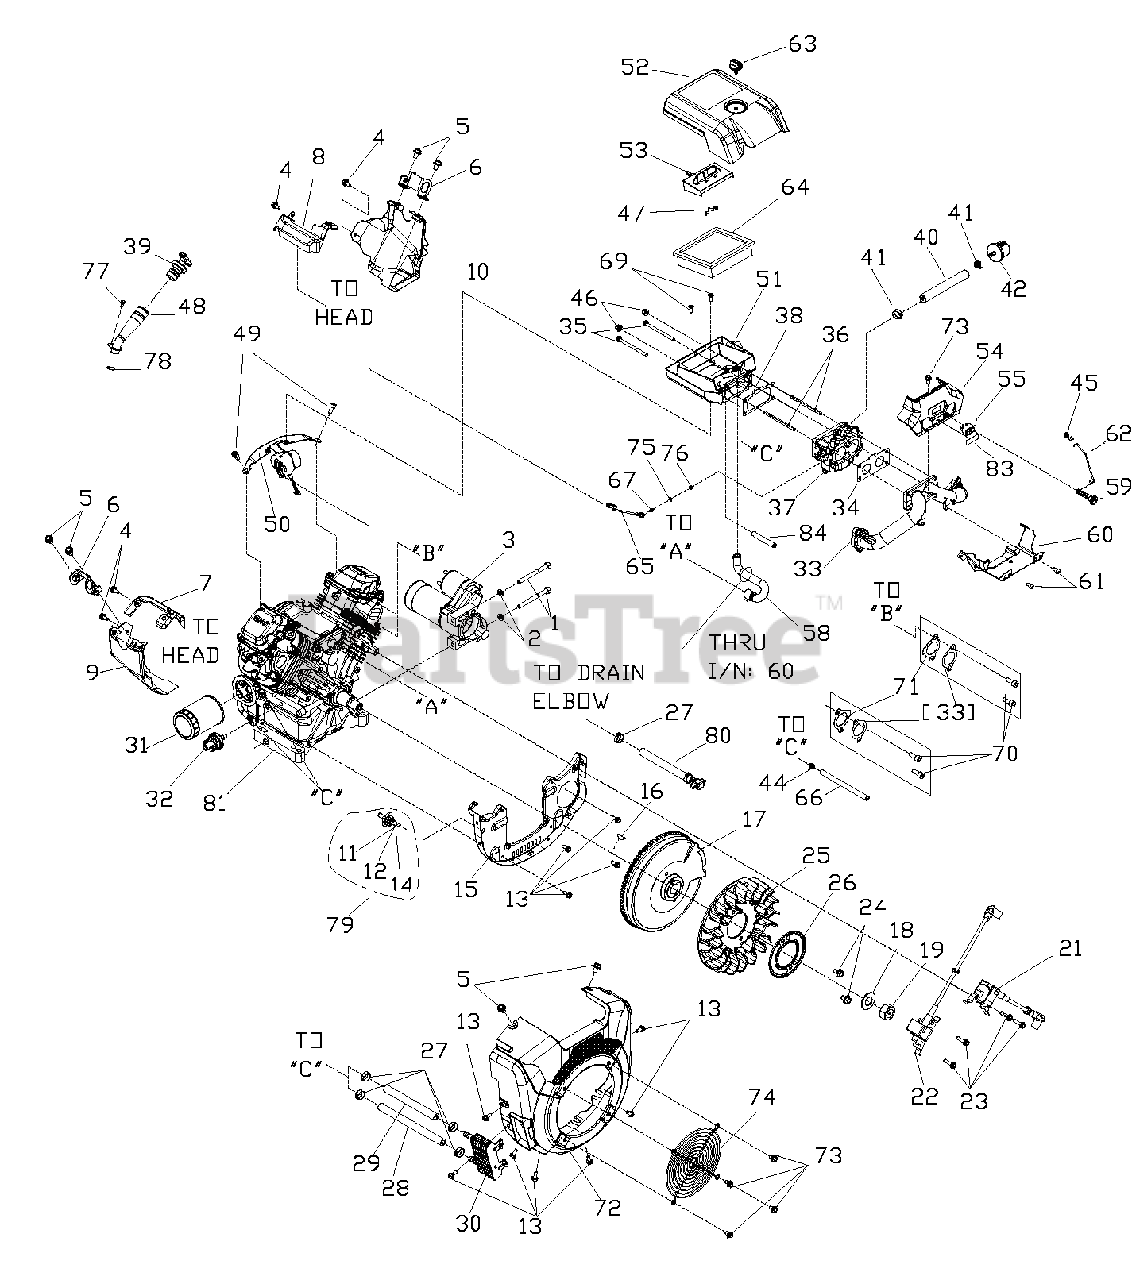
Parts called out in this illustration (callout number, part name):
1	SCREW HHC M8-1.25 X85
2	WASHER LOCK M8-5/16
3	STARTER MOTOR
4	SCREW HHFC M6-1.0 X 12
5	SCREW HHFC M8-1.25 X 14
6	LIFTING HOOK
7	WRAPPER INNER CYL #2
8	WRAPPER INNER CYL #1
9	WRAPPER OUTER CYL #2
10	WRAPPER OUTER CYL #1
11	SCREW CONNECTOR
12	GROUND POST MOUNT BLOCK
13	SCREW HHFC M6-1.0 X 8
14	NUT HEX M5 X 0.8
15	BACKPLATE GT530
16	KEY WOODRUFF 4X19
17	ASSY FLYWHEEL & RING 29 DEG
18	WASHER BEL V-20 X 2.2
19	HEX NUT METRIC
21	ASSY IGN COIL W/DIODE CYL #1
22	ASSY IGN COIL W/DIODE CYL #2
23	SCREW HHC M6-1.25 X 25 SEMS
24	SCREW HHFCS M8-1.25 X 12
25	FAN FLYWHEEL
26	PLATE FAN
27	CLAMP HOSE OETIKER STEPLESS 18.5
28	HOSE 3/8" PUSH-ON (191MM)
29	HOSE 3/8" PUSH ON (152MM)
30	OIL COOLER
31	FILTER OIL 90MM NO BRAND
32	SWITCH LOW OIL PRESSURE
33	MANIFOLD INTAKE GT530
34	GASKET INTAKE MANIFOLD TO CARB/MIXER
35	BOLT CARB MOUNT
36	STUD M6-1.0 X 90 DRI-LOC
37	CARBURETOR
38	GASKET AIRBOX TO CARB / MIXER
39	ASSY DIPSTICK
40	HOSE 1/4" GREENBAR SAE30R7 6"
41	CLAMP HOSE BAND 0.530
42	FILTER, FUEL
44	CLAMP HOSE BAND 0.409
45	BUSHING GOVERNOR ROD
46	NUT FLANGE M6-1.0 NYLOK
47	SPRING SUMMER / WINTER
48	ASSY OIL CHECK AND FILL
49	SCREW SHC M8-1.25 X 16
50	ELECTRONIC GOVERNOR STEPPER MOTOR
51	BASE AIRBOX
52	COVER AIRBOX
53	VALVE SUMMER / WINTER
54	COVER FRONT GTH530
55	SWITCH MOMENTARY (OFF) - ON
58	BREATHER HOSE
59	KNOB CHOKE
60	BAFFLE CENTER
61	SCREW BHSC M6-1.0 X 12
62	ROD MANUAL CHOKE
63	KNOB AIRBOX QUARTER-TURN
64	AIR FILTER ELEMENT
65	ASSY THROTTLE ROD
66	HOSE 11MM OD X 5.5MM ID X 30"
67	BALL STUD 8MM
69	SCREW PFHM M6-1.0 X 16
70	SCREW SHC M8-1.25 X 25 SEMS
71	GASKET INTAKE
72	BLOWERHOUSING
73	SCREW HHFCS M6-1.0 X 10
74	GUARD FAN
75	SPACER THROTTLE ROD
76	NUT HEX LOCK
77	SCREW HHSW M5-0.5 X 10
78	O-RING 9/16 X 3/4 X 3/32
79	ASSY GROUND WIRE CONNECTOR
80	ASSYEMBLY OIL DRAIN HOSE
81	ASSY BLOCK GTH530 GAS PORT
83	DECAL IGNITION
